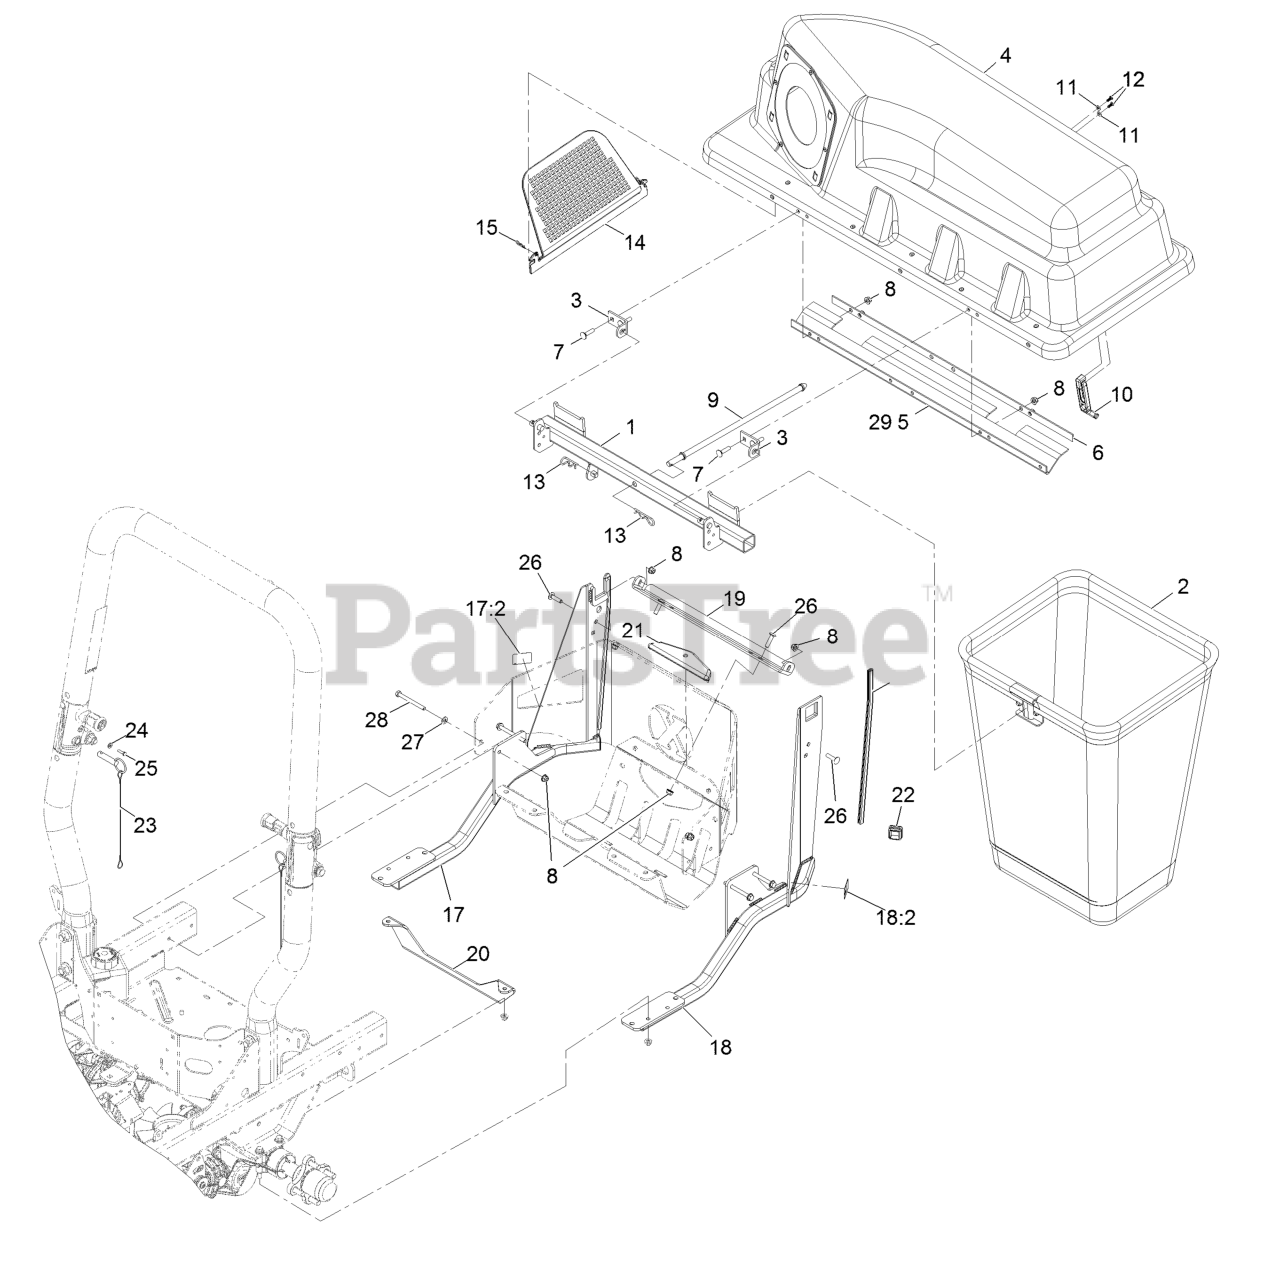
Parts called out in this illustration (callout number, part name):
1	Frame Pivot ASM
2	Bag And Frame ASM
3	Bracket-Pivot, Hopper
4	Bagger Hood ASM
6	Plate-Backing
7	Bolt-Carriage 5/16-18 X 1 1/4
8	Nut-Nyloc 5/16-18 Flg
9	Rod-Hold Down, Hood
10	Latch-Rubber
11	Washer-Flat
12	Screw-Plastite
13	Pin-Hair
14	Screen-Bagger
15	Pin-Cotter
17	RH Bagger Support ASM
17:2	Decal-Warning
18	LH Bagger Support ASM
18:2	Decal-Warning
19	Angle-Support
20	Support-Transmission
21	Cover-Hitch
23	Hitch Pin ASM
24	Washer-#10 Std
26	Screw-CARR
27	Washer-5/16 SAE
28	Screw-HH
29	Strip-Trim
